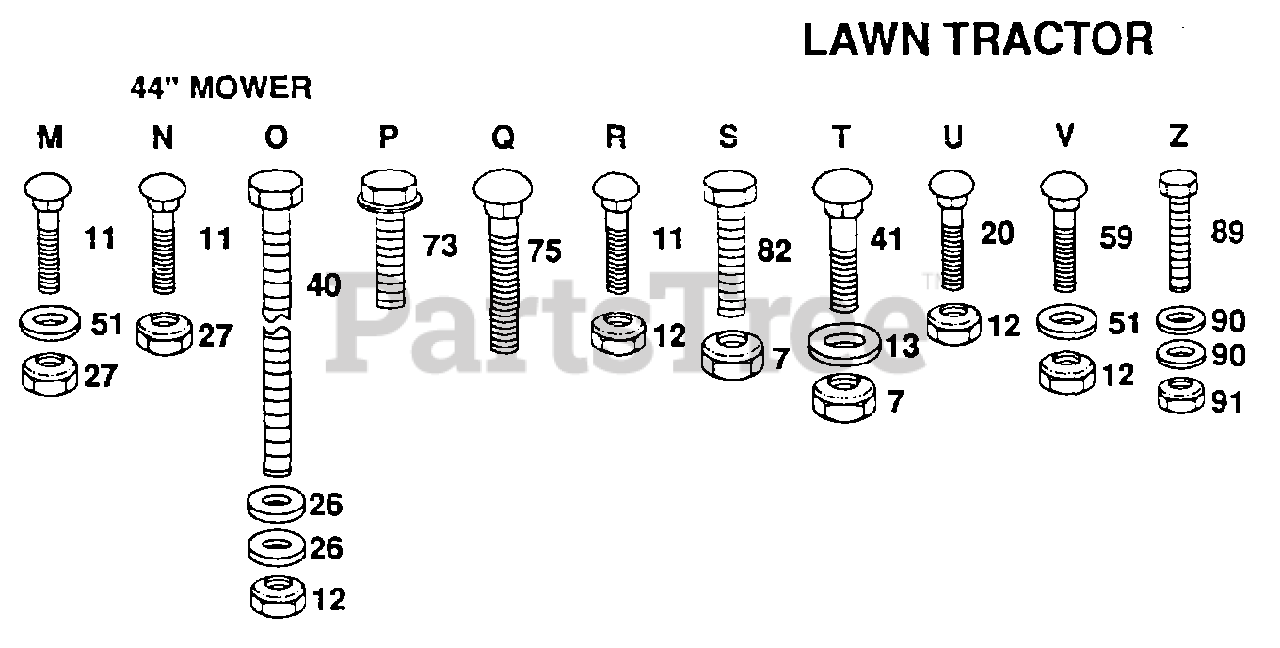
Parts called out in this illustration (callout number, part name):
11	BOLT
13	WASHER
20	BOLT
26	WASHER M
40	BOLT - HEX 3/8 - 16 X 3
51	WASHER
73	SCREW
75	BOLT
82	BOLT
89	BOLT LT
90	WASHER
